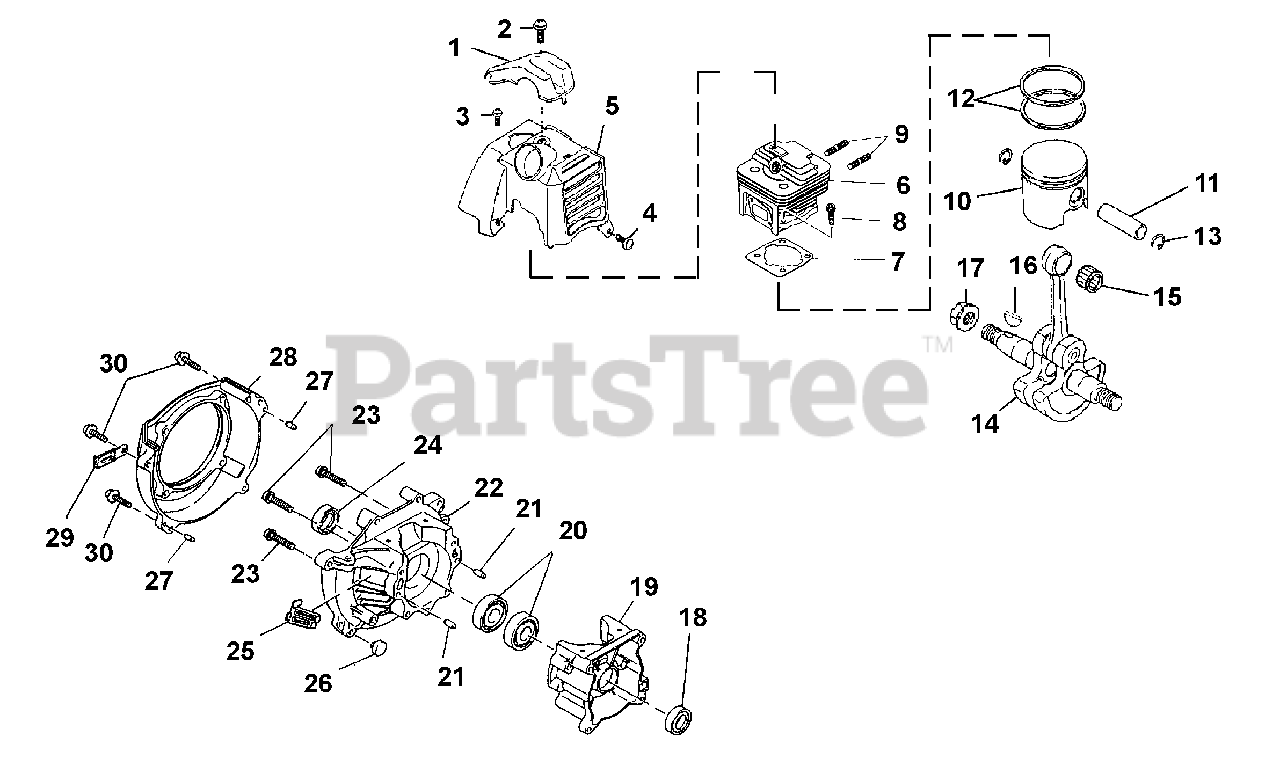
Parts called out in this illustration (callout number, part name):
1	Plug Guard
2	Screw & Washer
3	Screw & Washer
4	Screw & Washer
5	Top Cover
7	Gasket, Cylinder
8	Bolt & Washer
10	Piston Assembly
11	Pin, Piston
12	Ring, Piston
13	Clip, Piston Pin
14	Crankshaft
15	Needle Bearing
16	Woodruff Key
17	Nut
18	Oil Seal
19	Case, Starter
20	Ball Bearing
21	Dowel Pin
22	Case, Drive
23	Screw & Washer
24	Oil Seal
25	Cover, Crankcase
26	Pad, Fuel Tank
27	Dowel Pin
28	Case, Fan
30	Screw & Washer
